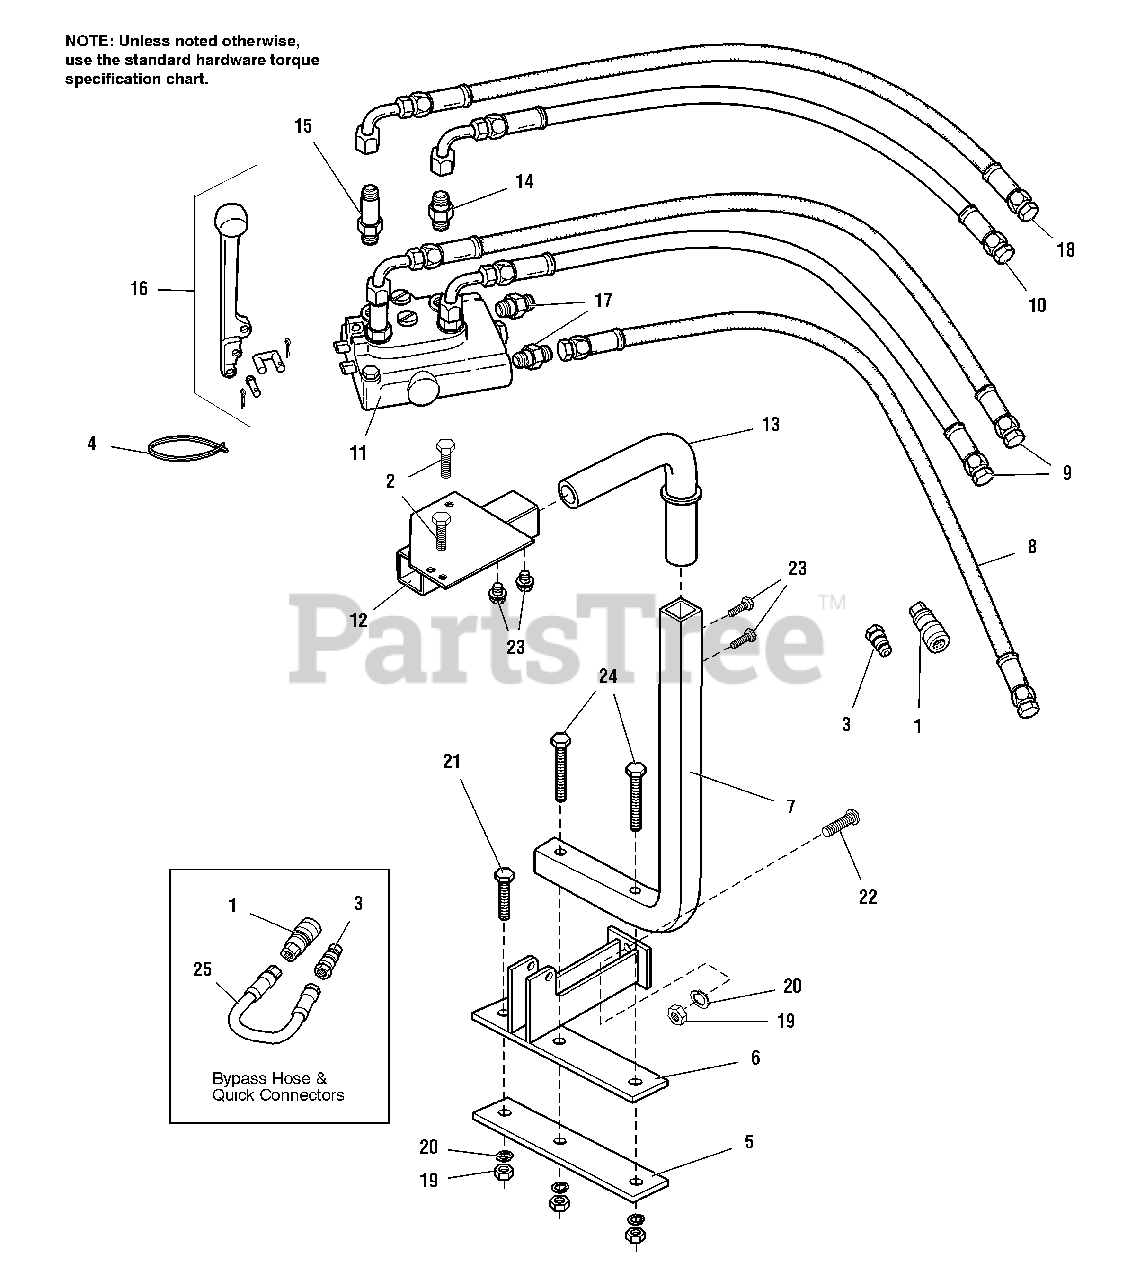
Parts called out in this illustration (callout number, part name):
1	QUICK CONNECTOR, Female Nose Piece Assembly
2	CAPSCREW, Hex Washer Hd, Taptite, 1/4-20 X 1-3/4
3	QUICK CONNECTOR, Male Nose Piece Assembly
4	TIE, Self-Locking
5	PLATE, Clamp, 5/16
6	SUPPORT ASSEMBLY
7	TOWER ASSEMBLY
8	HOSE, Hydraulic, 23/32" x 40"
9	HOSE, Hydraulic, 1/2" x 75"
10	HOSE, Hydraulic, 1/2" x 67"
11	CONTROL VALVE, Two Spool, Power Beyond
12	PLATE ASSEMBLY, Control Valve Mounting
13	TUBE ASSEMBLY, Control Tower Pivot
14	FITTING, Tube, Male, Short
15	FITTING, Tube, Male, Tall
16	KIT, Control Lever & Pin
17	FITTING, Tube, Male
18	HOSE, Hydraulic, 1/2 x 69"
19	NUT, Hex, 1/2-13
20	WASHER, Lock, 1/2
21	CAPSCREW, Hex Hd, 1/2-13 X 3-1/2
22	CAPSCREW, Hex Hd, 1/2-13 x 1-1/2
23	CAPSCREW, Hex Hd, 5/16-18 X 3/4
24	CAPSCREW, Hex Hd, 1/2-13 x 5, Gr 8
25	HOSE, Hydraulic, 1/2" x 11"
